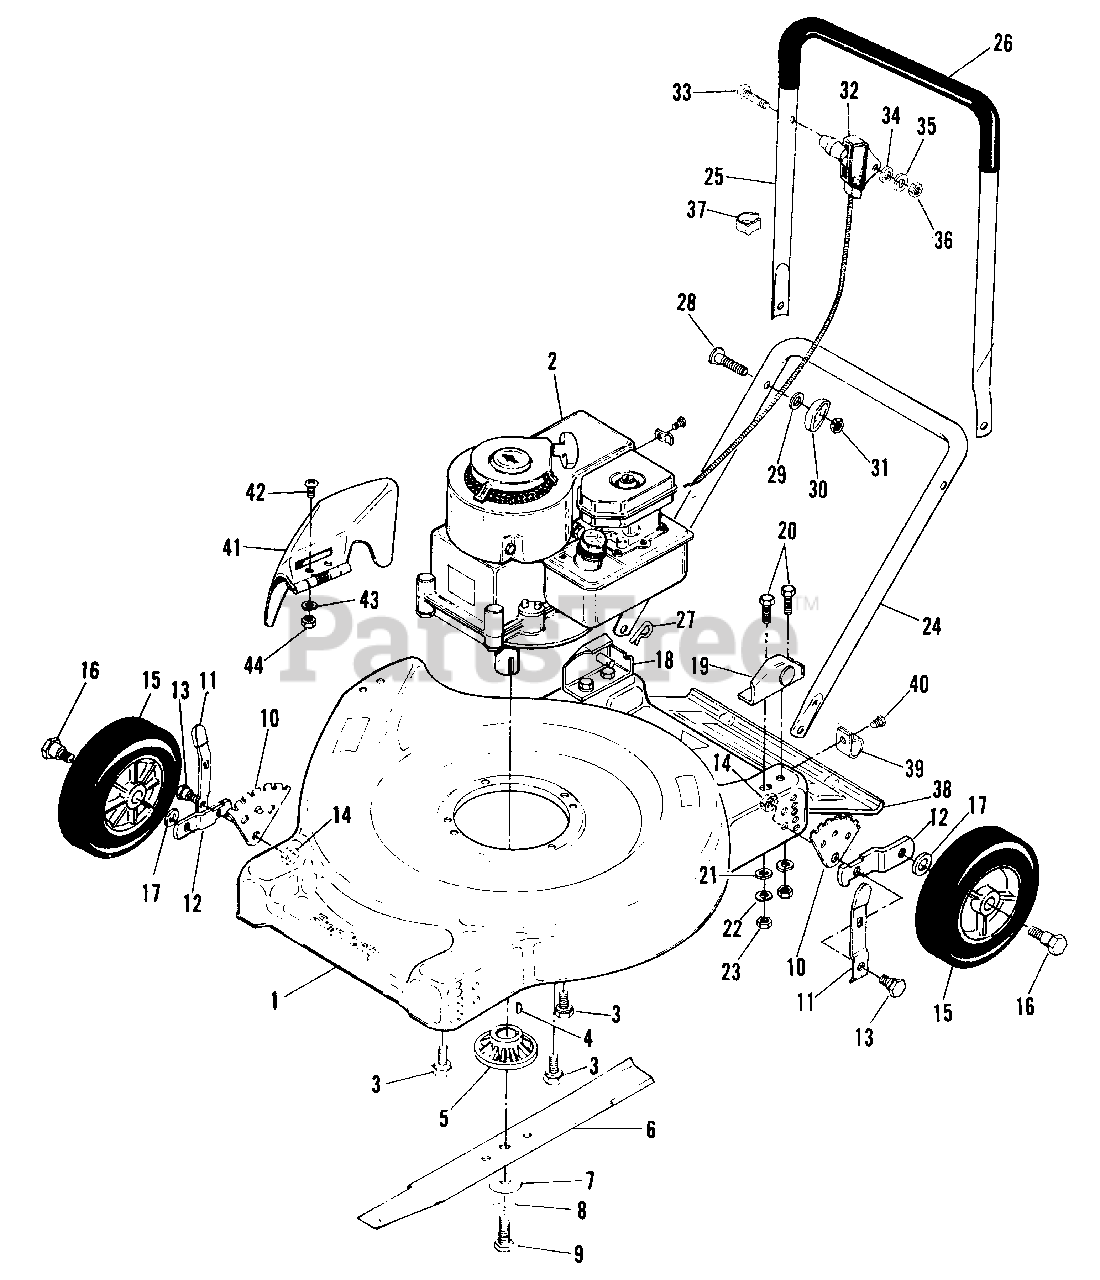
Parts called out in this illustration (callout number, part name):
1	HOUSING ASSY
2	ENGINE, 3.5 HP
3	SCREW, Hex w/Tooth Lockwasher
5	ADAPTOR, Blade
7	WASHER, Plain
8	LOCKWASHER
10	QUADRANT, Height Adj.
11	HANDLE ASSY, Height Adj.
12	ARM, Height Adj.
13	BOLT, Shoulder
15	WHEEL & TIRE ASSY
16	BOLT, Shoulder
17	WASHER, Plain
18	BRACKET ASSY, R.H.
19	BRACKET ASSY, L.H.
20	CAPSCREW, Hex Hd.
21	WASHER, Plain
22	LOCKWASHER
23	NUT, Hex, Full
24	HANDLE, Lower
25	HANDLE, Upper
26	TUBING, Handle
27	PIN, Cotter
28	BOLT, Curved Hd.
29	WASHER, Plain
30	NUT, Wing
31	NUT, Hex, Lock
32	CONTROL, Throttle
34	WASHER, Plain
35	LOCKWASHER
36	NUT, Hex
38	SHIELD, Rear Safety
39	CLAMP, Tube
40	SCREW, Hex, Washer Hd.
41	DEFLECTOR ASSY, Discharge
42	SCREW, Rd. Hd. Phillips
43	LOCKWASHER
44	NUT, Hex
